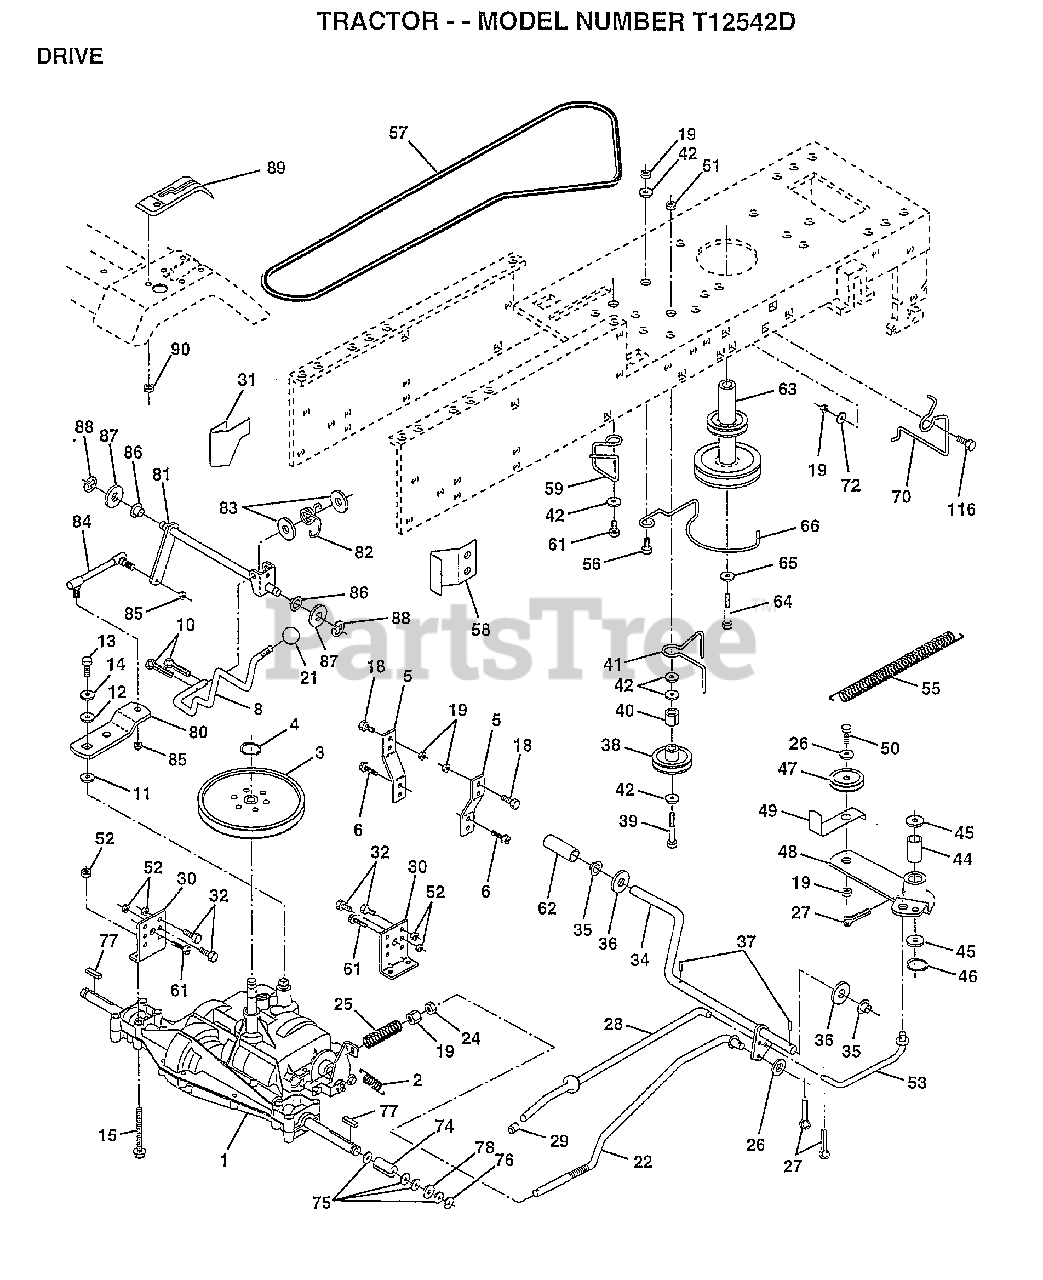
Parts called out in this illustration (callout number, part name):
2	SPRING.BRAKE.RETU
3	PULLEY TRANS
5	STRAP TORQUE
6	SCREW
8	SHIFT ROD
10	PIN COTTER 1/8
11	WASH-SHFT PLT LT
12	WASHER
13	BOLT.1/4-28.W/PAT
14	LOCKWASHER
15	BOLT.HX.FLG.5/16
18	BOLT
19	NUT
21	CONTROL KNOB LT
22	BRAKE ROD
24	NUT
25	SPRING ROD LT
26	WASHER
27	COTTER PIN
28	ROD.BRAKE.PARK.LT
30	TRANSAXLE MTG BKT
31	"KEEPER,BELT LH T"
32	BOLT
34	SHAFT.PEDAL.FOOT
35	NYLON BEARING
36	WASHER LT
38	PULLEY.IDLER.FLAT
39	BOLT
40	SPACER T
41	BELT KEEPER LT
42	WASHER
44	"LY, BEARING"
45	WASHER LT
46	KLIP RING
48	ARM IDLER
49	RETAIN BELT
53	"LINK, CLUTCH T"
55	"SPRING, RETURN LT"
58	"KEEPER,BELT RH T"
59	KEEPER BELT CNTSP
61	SCREW
62	PEDAL COVER T
63	PULLEY.ENGINE
64	BOLT
65	LOCKWASHER
66	KEEPER.BELT.ENG.L
70	KEEPER BELT ENG
72	WASHER
74	SPACER LT
76	E-RING LT
77	SQUARE KEY
78	WASHER
112	WASHER LT
116	BOLT RDHD 3/8-16
